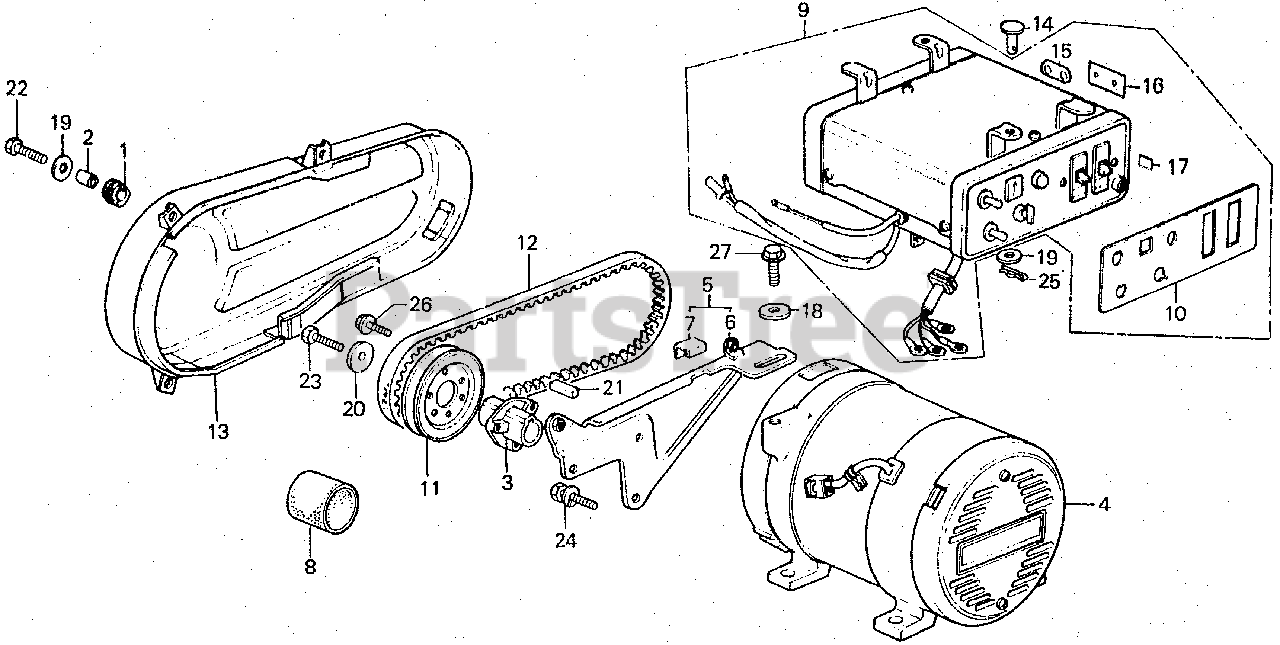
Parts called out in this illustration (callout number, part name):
1	RUBBER, TANK CUSHION (NOT AVAILABLE)
2	COLLAR, DISTANCE
3	BOSS, DRIVE PULLEY (NOT AVAILABLE)
4	GENERATOR ASSY. *R8/NH31/NH1* (BRIGHT RED/MC KINLEY WHITE/ BLACK) (NOT AVAILABLE)
5	STAY ASSY., GENERATOR (NOT AVAILABLE)
6	STAY, GENERATOR (NOT AVAILABLE)
7	SEAT, RUBBER
8	PROTECTOR, STARTER
9	BOX ASSY., CONTROL *R8* (BRIGHT RED)
10	MARK, CONTROL BOX PANEL (NOT AVAILABLE)
11	PULLEY (141MM) (NOT AVAILABLE)
12	V-BELT (B-38) (NOT AVAILABLE)
13	COVER, BELT *R8* (BRIGHT RED) (NOT AVAILABLE)
14	PIN, CONTROL BOX SETTING
15	MARK, D.C. CAUTION
16	MARK, A.C. OUTPUT
17	MARK, GROUND
18	WASHER (10X30X3.5T)
19	WASHER, FLAT (20MM)
20	WASHER, LOCK (8MM)
21	KEY (7X7X33) (YELLOW)
22	BOLT, HEX. (6X20)
23	BOLT, HEX. (8X25)
24	BOLT-WASHER (8X20)
25	PIN, LOCK (8MM)
26	BOLT, FLANGE (6X16)
27	BOLT, FLANGE (10X25)
